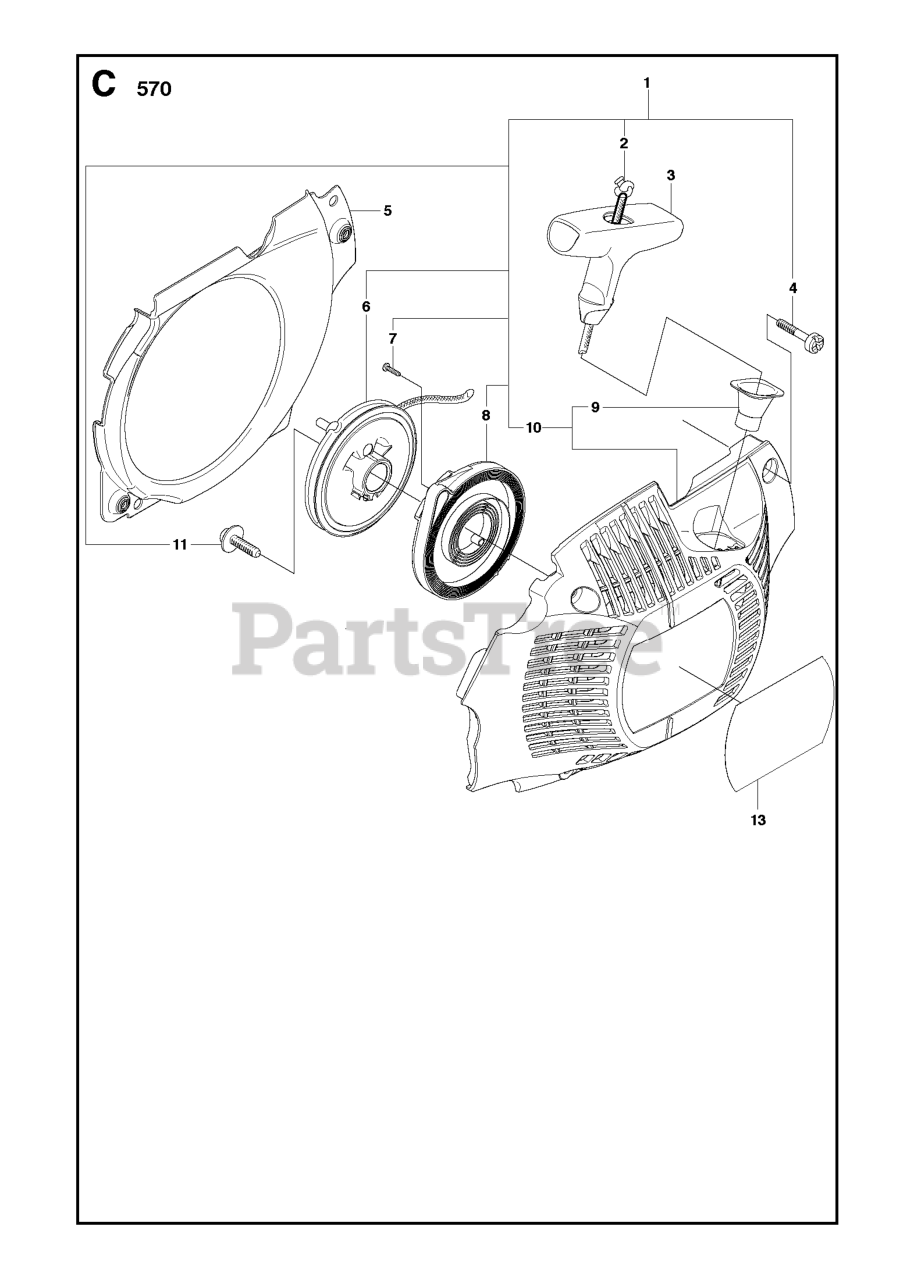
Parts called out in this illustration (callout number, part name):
1	STARTER ASSY COMPLETE
1	STARTER ASSY
2	STARTER ROPE
4	SCREW.CIHPANMO M5X19 10.9
6	STARTER PULLEY
10	STARTER COVER
10	STARTER HOUSING
